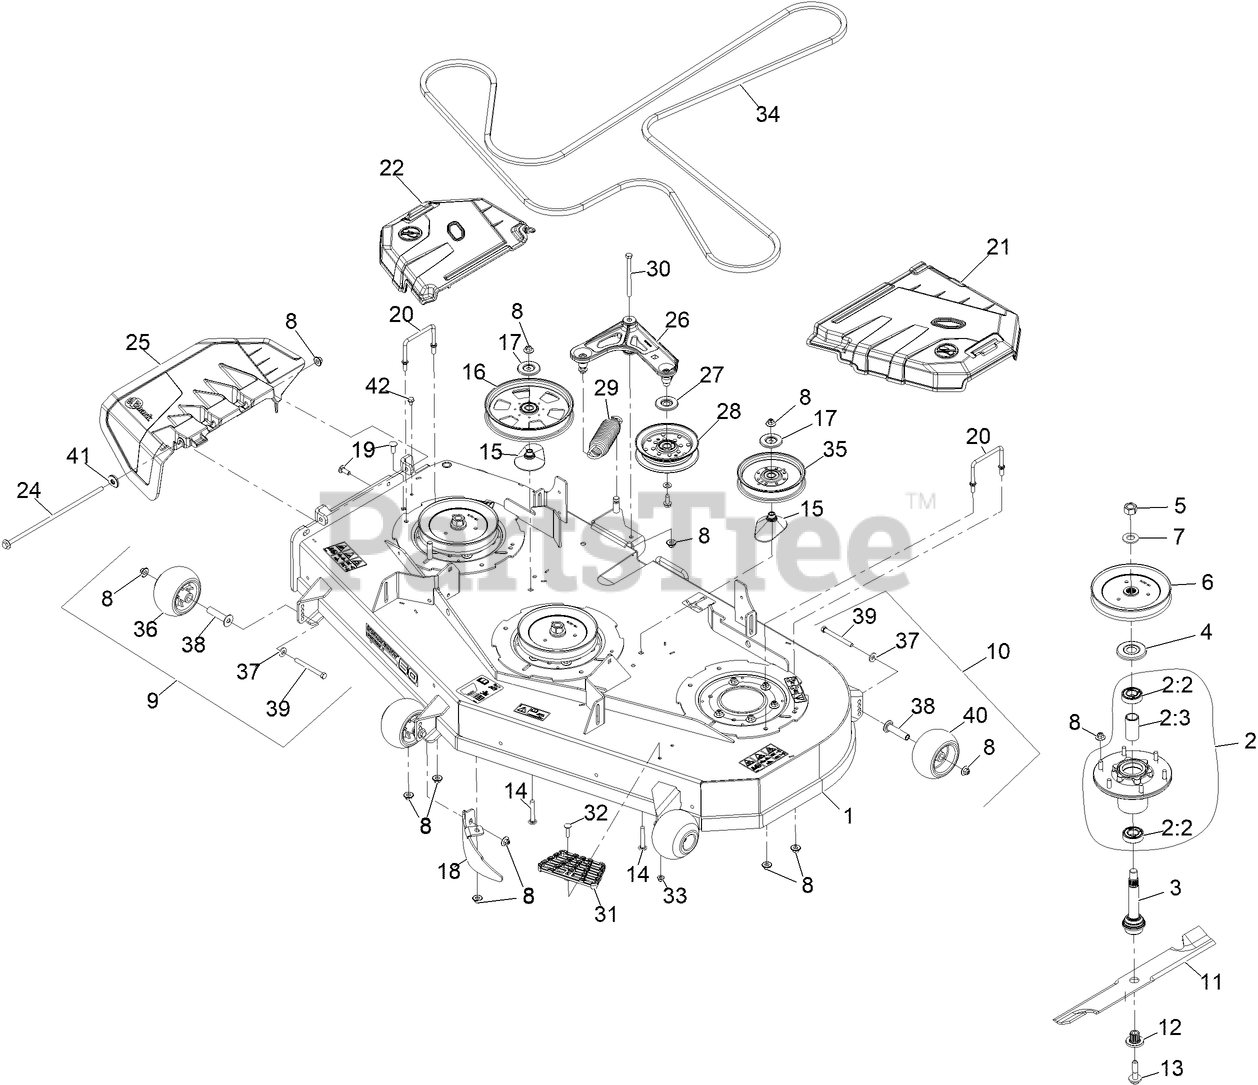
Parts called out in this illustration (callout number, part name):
1	ASM-Deck W/Decals 604
2	ASM-CUTTER HSG WITH BEARINGS
2:2	BEARING-BALL
2:3	SPACER-BEARING
3	ASM-SPINDLE AND SEAL
4	GUARD-BEARING, TOP
5	NUT-HEX
6	SHEAVE,BLADE DRIVE 7.25
8	Nut-Nyloc 3/8-16 Flg
9	KIT, ANTI-SCALP ROLLER
10	KIT-ANTISCALP ROLLER
11	Blade-Extreme 2, 20.50"
12	BUSHING,SPLINED
13	SCREW,SEMS 1/2-20 X 2.19
14	SCREW-CARR
15	SPACER-PULLEY
16	PULLEY-IDLER, FLAT
17	SHIELD-DUST
18	DOGLEG - LZ60
19	SCREW-CARR
20	WIREFORM-COVER
21	SHIELD, LT
22	SHIELD, RT
24	Pin, Chute
25	Chute-Deck Discharge
26	ASM-IDLER ARM W/BEARINGS
27	SHIELD-GUARD, DUST
28	IDLER-PULLEY, FLAT
29	SPRING-EXTENSION
30	SCREW-HH
31	STEP-DECK
32	Bolt-Carriage 5/16-18 X 1 1/4
33	NUT-HF, NI
34	BELT-V
35	IDLER-PULLEY, FLAT 6.00X1.00
36	ROLLER-SCALP, ANTI
37	WASHER-BELLEVILLE
38	AXLE, ROLLER
39	SCREW-HH 3/8-16 X 3 3/4 GR 8
40	ROLLER-SCALP, ANTI
41	Retainer, Chute
42	SCREW-HHF
